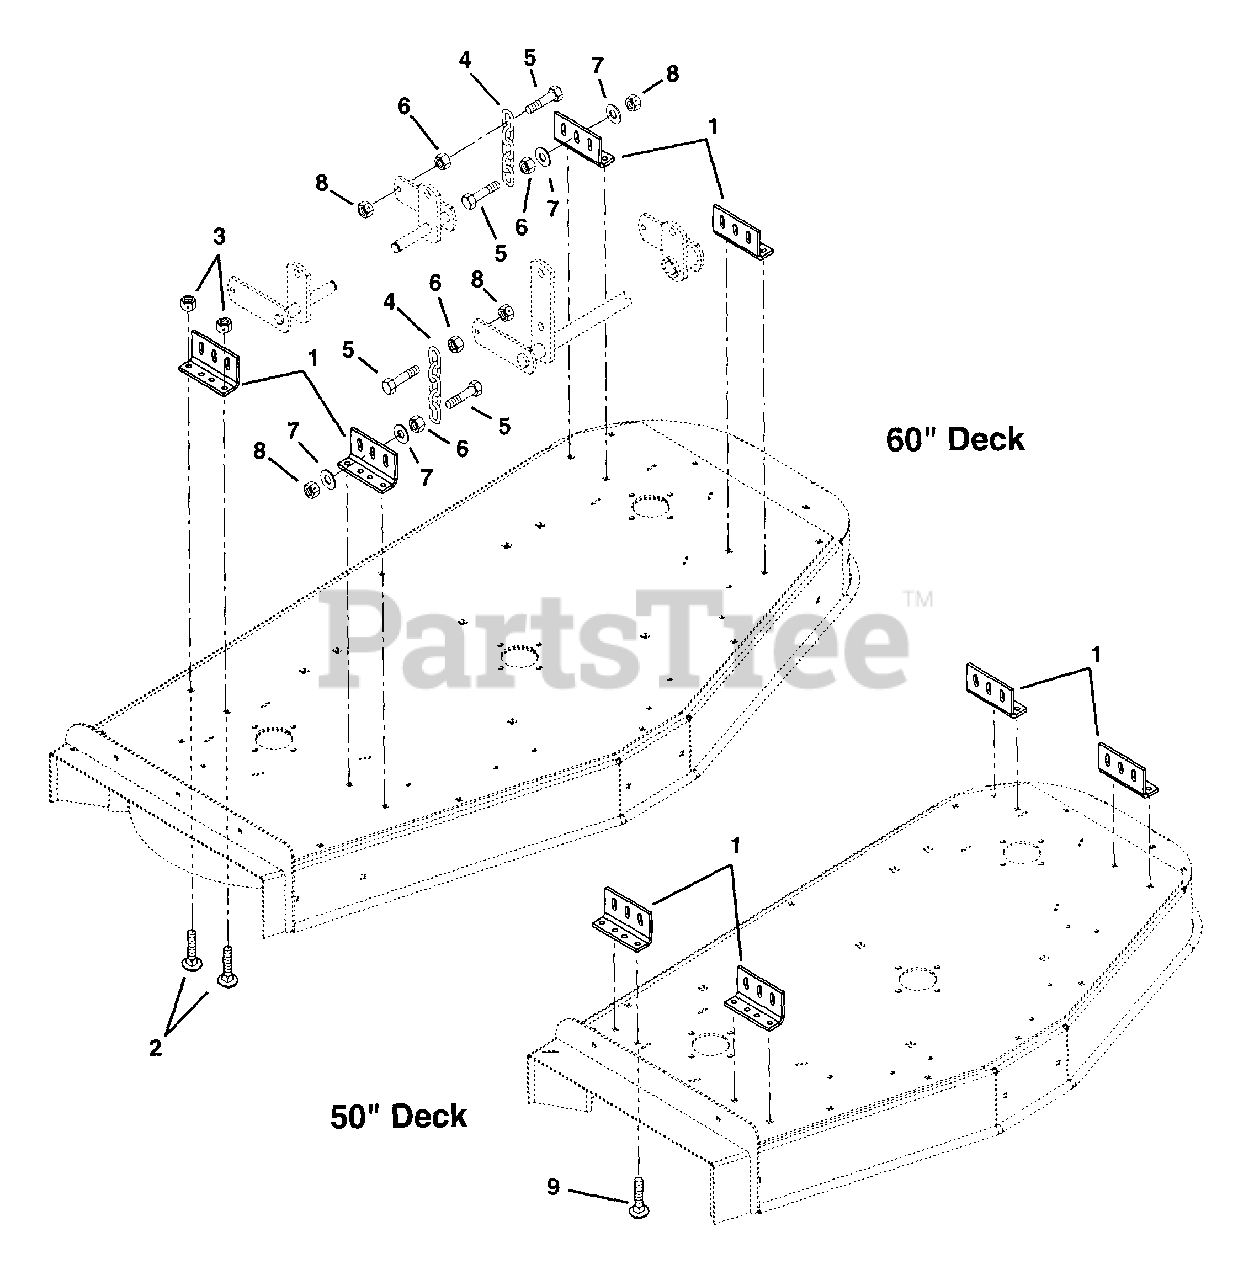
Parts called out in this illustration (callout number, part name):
1	Bracket, Mower Mounting
2	Bolt-Round Head Square Neck .38-16 x 1.25 Grade 2 (60" Deck)
2	Bolt-Round Head Square Neck .38-16 x 1.25 Grade 2 (50" Deck)
3	Nut-Locking-Nylon .38-16
4	Chain, Link
5	Bolt-Hex .38-16 x 1.50 Grade 5
6	Nut-Hex .38-16
7	Washer-Flat-Steel .406 x .812 x .065
8	Nut-Locking-Center .38-16
9	Bolt-Round Head Square Neck .38-16 x 1.50 Grade 2 (50" Deck)
